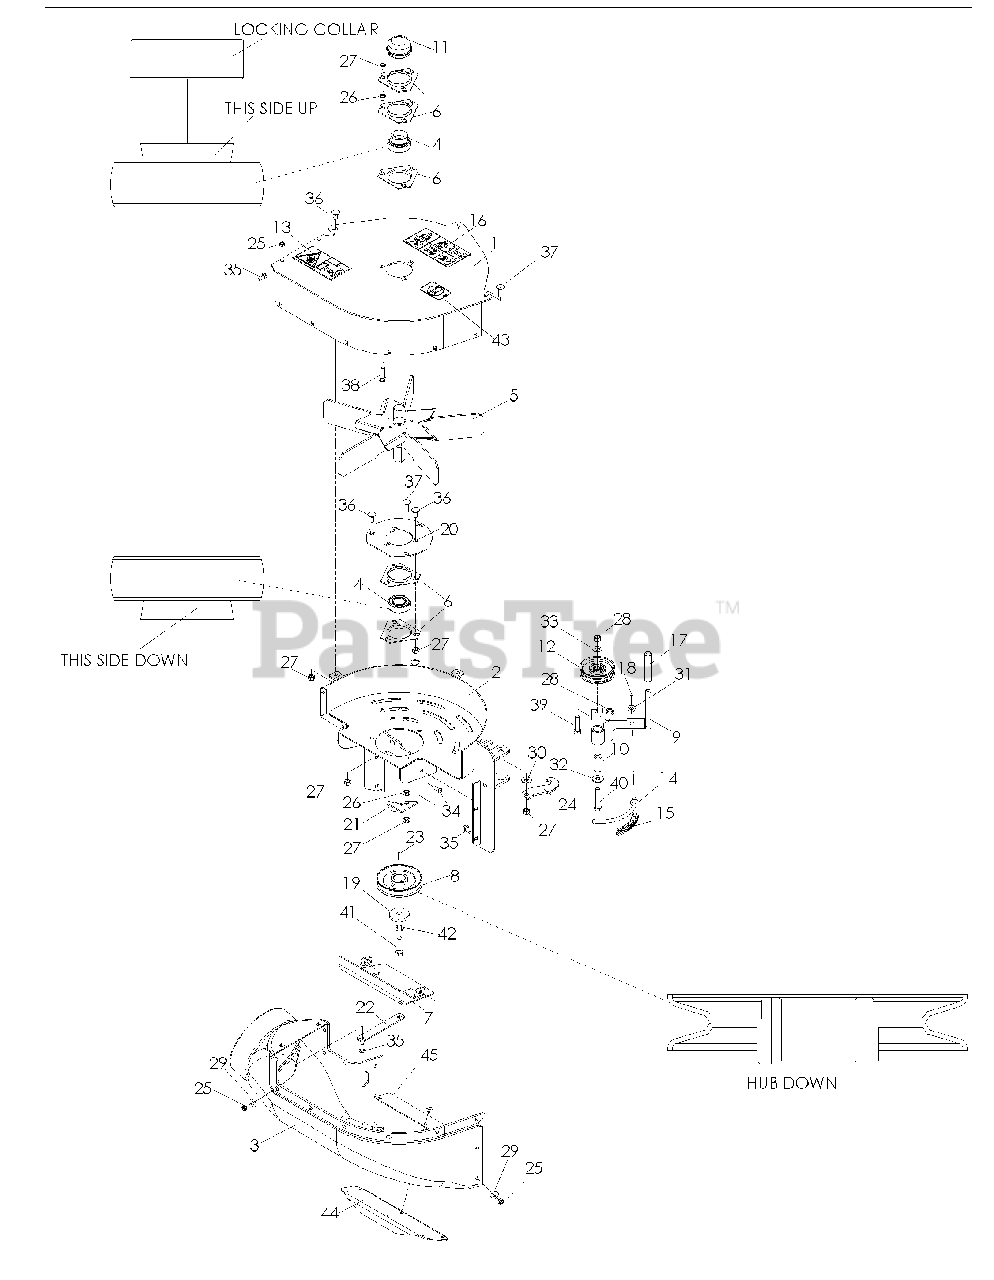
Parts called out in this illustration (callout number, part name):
1	FAN COVER W/DECALS
2	BLOWER HOUSING
3	LOWER HOUSING
7	COVER PLATE
8	SHEAVE, 4"
10	SLEEVE BUSHING
11	CAP, GREASE
13	DECAL, SEVERING
14	SPRING ROD
16	DECAL, WARNING
17	GRIP, VINYL
18	PIN, COTTER 3/32 x 3/4
19	HEAVY WASHER
20	BEARING PLATE
21	BELT GUIDE
23	KEY 1/4 SQ x 3/4
24	IDLER ARM KEEPER
25	NUT 1/4-20, THIN, NYLOC
26	NUT 5/16-18 HEX NYLOC
27	NUT 5/16-18 HEX NYLOC
28	NUT 3/8-16 CENTERLOCK
29	WASHER 1/4
30	WASHER 5/16 STD FLT
31	WASHER 5/16 SAE
32	WASHER 3/8 STD FLT
33	WASHER 3/8 SAE FLT
34	SCREW, 1/4-20 x 5/8 BTN
35	RHSNB 1/4-20 x 3/4 GR2
36	RHSNB 5/16-18 x 3/4
37	RHSNB 5/16-18 x 1
38	RHSNB 5/16-18 x 1 1/4
39	HCS 3/8-16 x 1 1/2
40	HCS 3/8-16 x 2
41	HCS 7/16-20 x 1 1/2
42	LOCKWASHER 7/16
43	DECAL, NO STEP
44	BLOWER SUPPORT
45	PLATE, BLOWOUT
